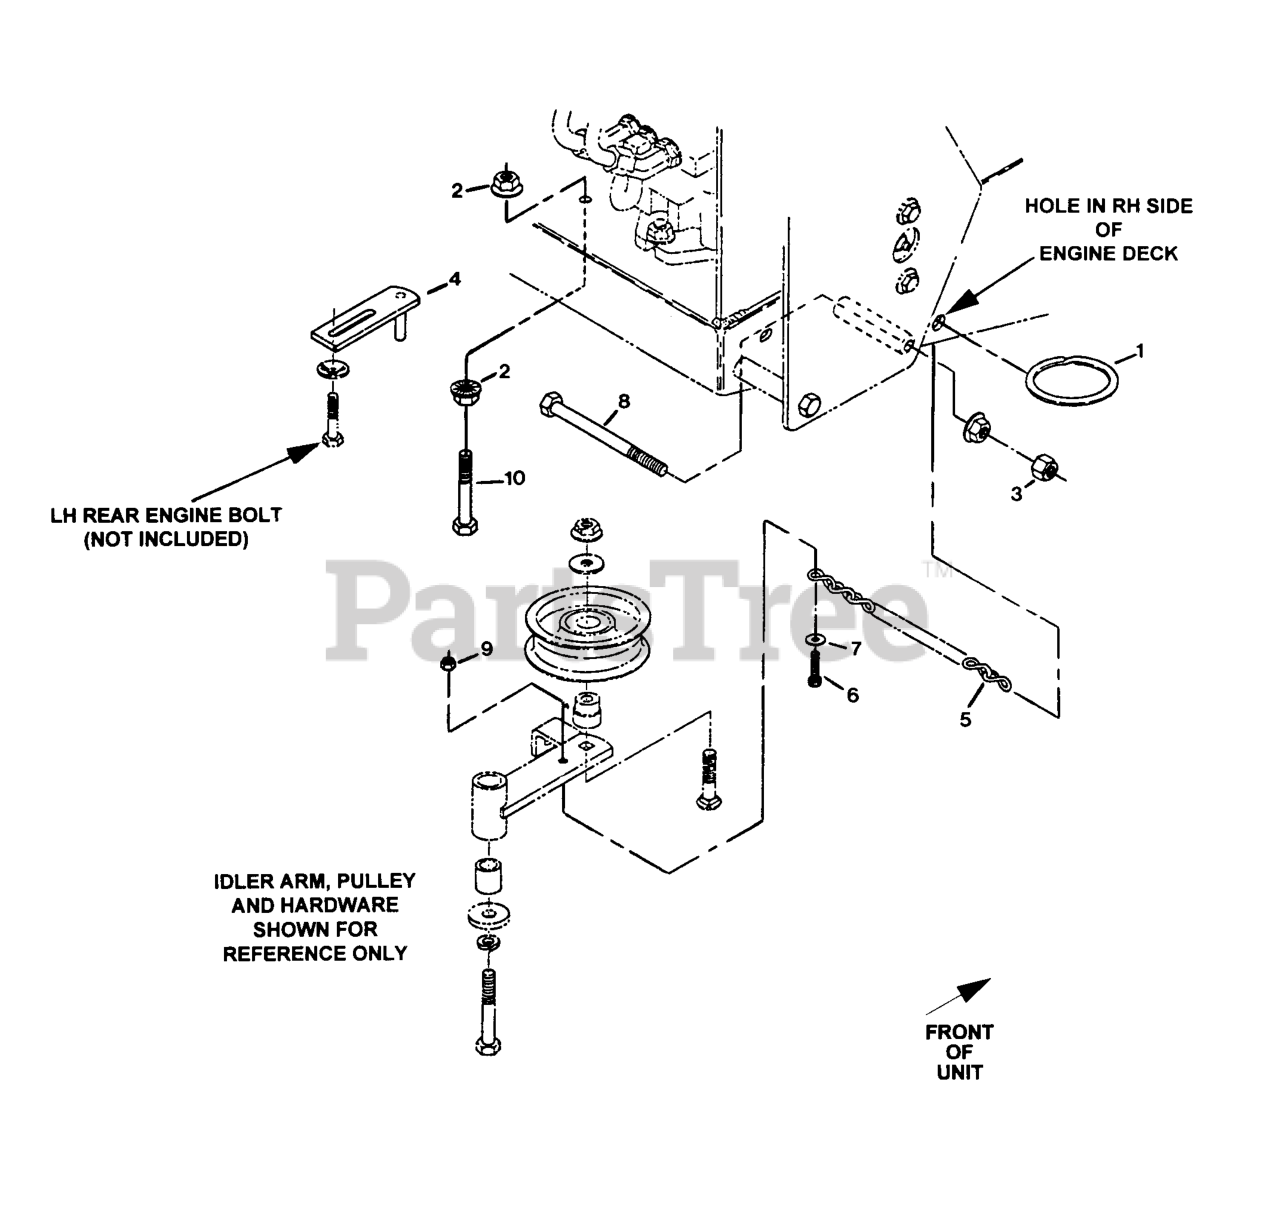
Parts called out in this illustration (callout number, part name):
1	RING-SPLIT
4	GUIDE-BELT
5	CHAIN-LINK, TWIST
6	SCREW-HSH
